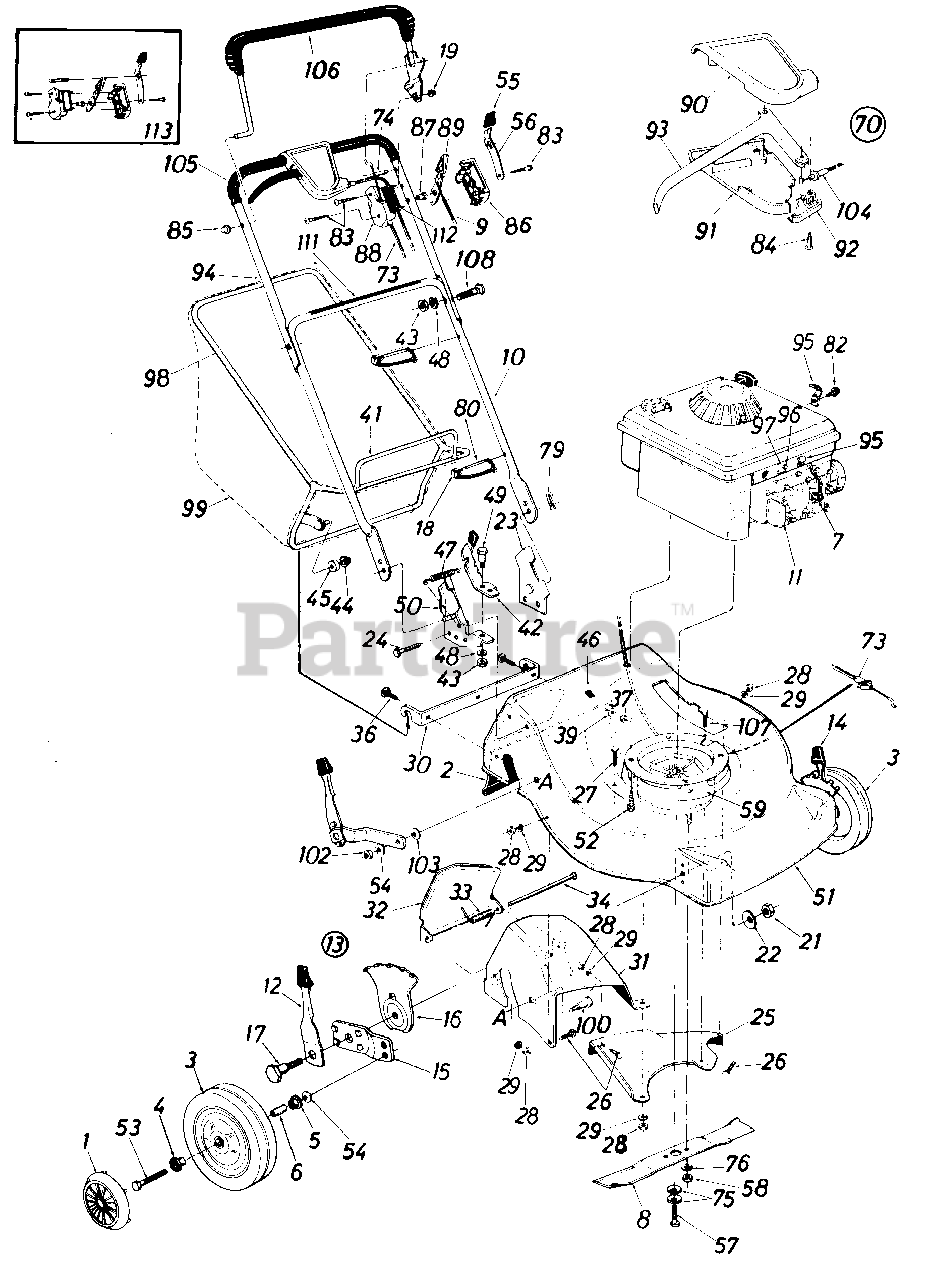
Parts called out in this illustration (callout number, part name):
1	Hub Cap-Plastic
2	Rear Flap Ass'y.
3	Front Wheel Ass'y. Comp.
4	Bearing
5	Bearing
6	Spacer
7	Spark Plug Boot
8	22" Blade
9	Throttle Control Wire-58"
10	Lower Handle (Chrome)
11	Engine
12	Spring Lever Ass'y. w/Knob
13	Height Adjust. Ass'y.-R.H.
14	Height Adjust. Ass'y.-L.H.
15	Pivot Bar
16	Index Plate
17	Shld. Bolt .50" Dia. x .375"
18	Cable Anchor
19	Push Cap
21	Hex Nut 3/8-16 Thd.
22	Bell-Wash. .39" I.D. x 1.38" O.D.
23	Handle Brkt. Ass'y.-L.H.
24	Hex Wash. Hd. AB-Tap Scr. 1/4" x.62" Lg.
25	Rear Baffle-L.H.
26	Carriage Bolt 1/4-20 x .50"
27	Hex Bolt 1/4-20 x .88" Lg.
28	Hex Nut 1/4-20 Thd.
29	L-Wash. 1/4" I.D.
30	Grass Catcher Hitch Brkt.
31	Rear Chute Baffle Ass'y.
32	Chute Door
33	Torsion Spring
34	Hinge Pin .250" Dia. 7.88" Lg.
36	Carriage Bolt 1/4-20 x .75"
37	Sems Nut 1/4-20 Thd.
39	Fl-Wash. .285" I.D. x 1.25"
43	Hex Nut 5/16-18 Thd.
44	Push Nut 3/8" Rod
45	Plastic Roller
47	Extension Spring .33" O.D. x 1.12" Lg.
48	L-Wash. 5/16" I.D.
49	Shld. Bolt .437" Dia. x .162"
50	Handle Brkt. Ass'y.-R.H.
51	22" Deck Ass'y.
52	Hex Wash. Hd. TT-Tap Scr. 3/8-16 x 1.0" Lg.
53	Axle Bolt
54	Bell-Wash. .44" I.D. x .88"
55	Spring Lever Knob
56	Lockout Lever
57	Hex Bolt 3/8-24 x 2.00" Lg. (Grade 8)
58	Hex Nut 3/8-24 Thd. (Grade 8)
59	Blade Brake Clutch Ass'y. Comp.
70	Clutch Control Housing-Comp.
73	Clutch Cable-46"
74	Lock Pin .314" Dia. x 1.70"
75	Bell-Wash. .44" I.D. x 88"
76	L-Wash. 3/8" I.D.
79	Intern. Cot. Pin 5/16" Dia.
80	Cable Tie
82	Hex B-Tap Scr. #10 x .38" Lg.
83	Truss Mach. Scr. #12 x 1.50"
84	Flat "C"-Sunk Hd. Scr. #10 x 1.0" Lg.
85	Cap Speed Nut 5/16" Rod
86	Control Panel Half
87	Control Disc Pin
88	Clutch Panel Half
89	Throttle Control Lever
90	Control Cover Half-Upper
91	Control Cover Half-Lower
92	Cable Mtg. Cap
93	Control Lever
94	Upper Handle (Chrome)
95	Casing Clamp
96	Hex B-Tap Scr. #10 x .62" Lg.
97	Casing Clamp
98	Grass Catcher Upper Frame
99	Grass Bag (without Flip Top)
100	Shld. Bolt .500" Dia. x .685"
102	Hex Jam Nut 3/8-16 Thd.
103	Bell-Wash..400" I.D.
104	Clutch Cable-50"
106	Blade Clutch Control Handle
107	Hex Wash. Hd. Self-Tap Scr. 1/4-20 x .75" Lg.
108	Curved Hd. Carr. Bolt 5/16-18 x 1.38
111	Instruction Label-Handle
112	Control Label-Throttle
113	Control Housing Comp.
